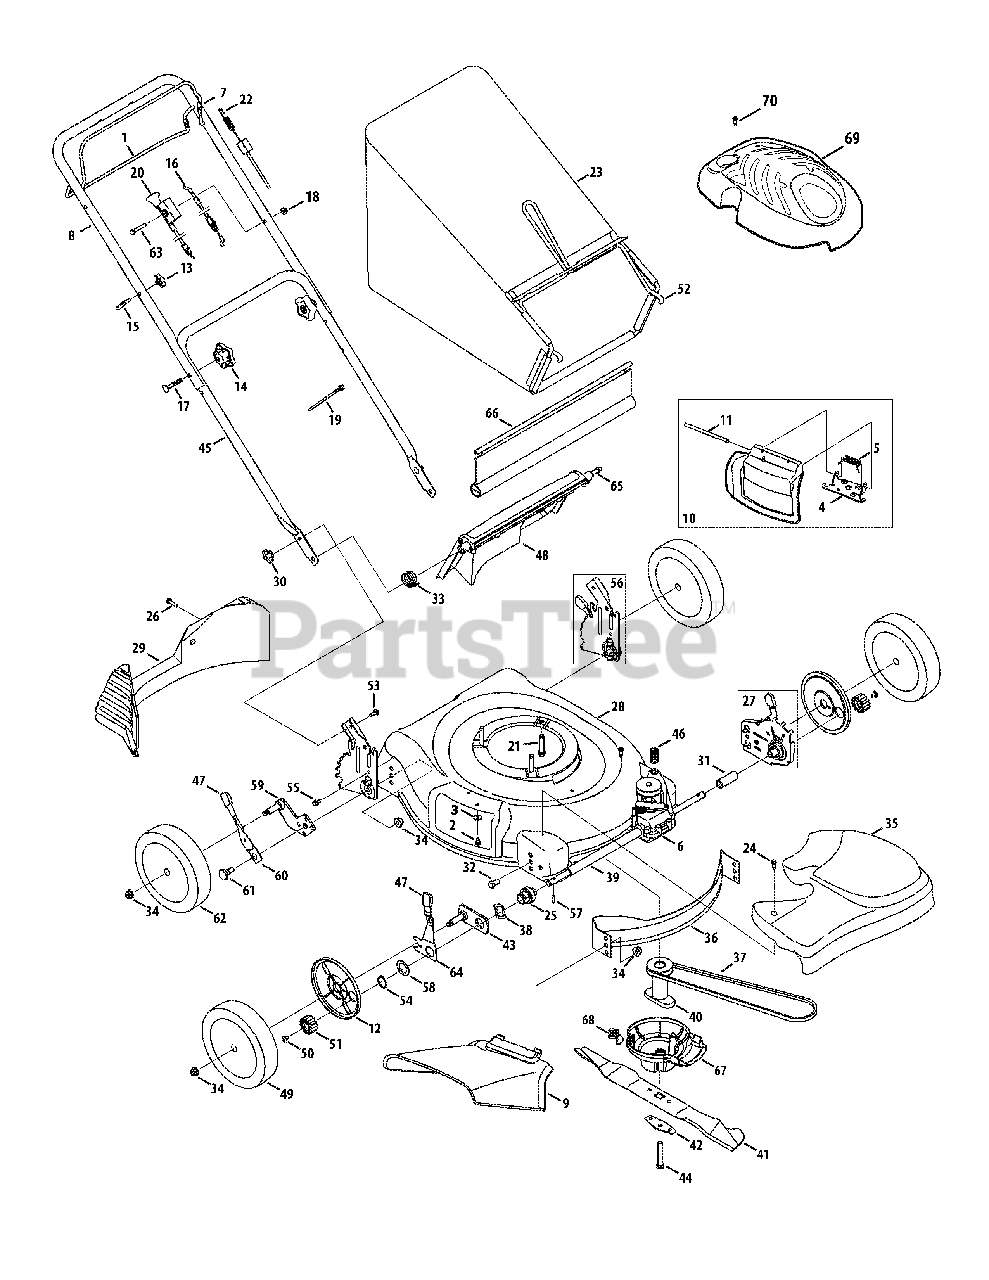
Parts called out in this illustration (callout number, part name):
1	Drive Control
2	TT Screw 1/4-20 x 0.5
3	Bell Washer.265 x 0.75
4	Deflector Chute Adapter
5	Torsion Spring
6	Transmission Assembly
7	Blade Control
8	Upper Handle
9	Chute Deflector
10	Mulch Plug Complete
11	Hinge Pin
12	Wheel Dust Cap
13	Handle Knob
14	Star Knob
15	Eye Bolt
16	Control Cable
17	Carriage Bolt 5/16-18 x 2.0
18	Nut, Flange Lock, 1/4-20
19	Cable Tie
20	Choke Cable
21	Self-Tapping Sems Screw
22	Drive Cable
23	Grassbag
24	Shoulder Screw # 12 -24
25	Front Bearing Assembly
26	Screw, 1/4-15 x 1.000
27	Height Adjustment Ass’y - RH
27	Height Adjustment Ass’y - LH
29	Rear Baffle
30	Wing Nut
31	Slev. Spacer 1.4" Lg.
32	Hex Screw, 3/8-16 x.75
33	Torsion Spring - RH
34	Flange Lock Nut, 3/8-16
35	Transmission Cover
36	Front Baffle
37	V-Belt
38	Wave Washer
39	Sleeve Spacer 8.985" Lg.
40	One Piece Blade Adapter
41	21" Mulching Blade
42	Blade Bell Support
43	Pivot Plate Assembly
44	Hex Screw 3/8-24 x 2.50
45	Lower Handle
46	Belt Tension Spring
47	Adjustment Knob
48	Rear Discharge Door
49	Front Wheel
50	Screw, 1/4-20 x .390
51	Gear 14T RH FWD
51	Gear 14T LH FWD
53	Carriage Bolt 1/4-20
54	Snap Ring
55	TT Scr. w/Washer 1/4-20 x.625
56	Handle Bracket Assembly - RH
56	Handle Bracket Assembly - LH
57	Dowel Pin
58	Washer
59	Pivot Arm Assembly - RH
59	Pivot Arm Assembly - LH
60	Rear Spring Lever
61	Shoulder Scr.500 Dia. x.434
62	Rear Wheel
63	Screw, 1/4-20 x 1.50
64	Front Lever - RH
64	Front Lever - LH
65	Pivot Rod
66	Rear Trailing Shield
67	Engine Baffle
68	Engine Baffle Bracket
69	Engine Shroud
70	Screw, HL, #12-16 x 1.00
